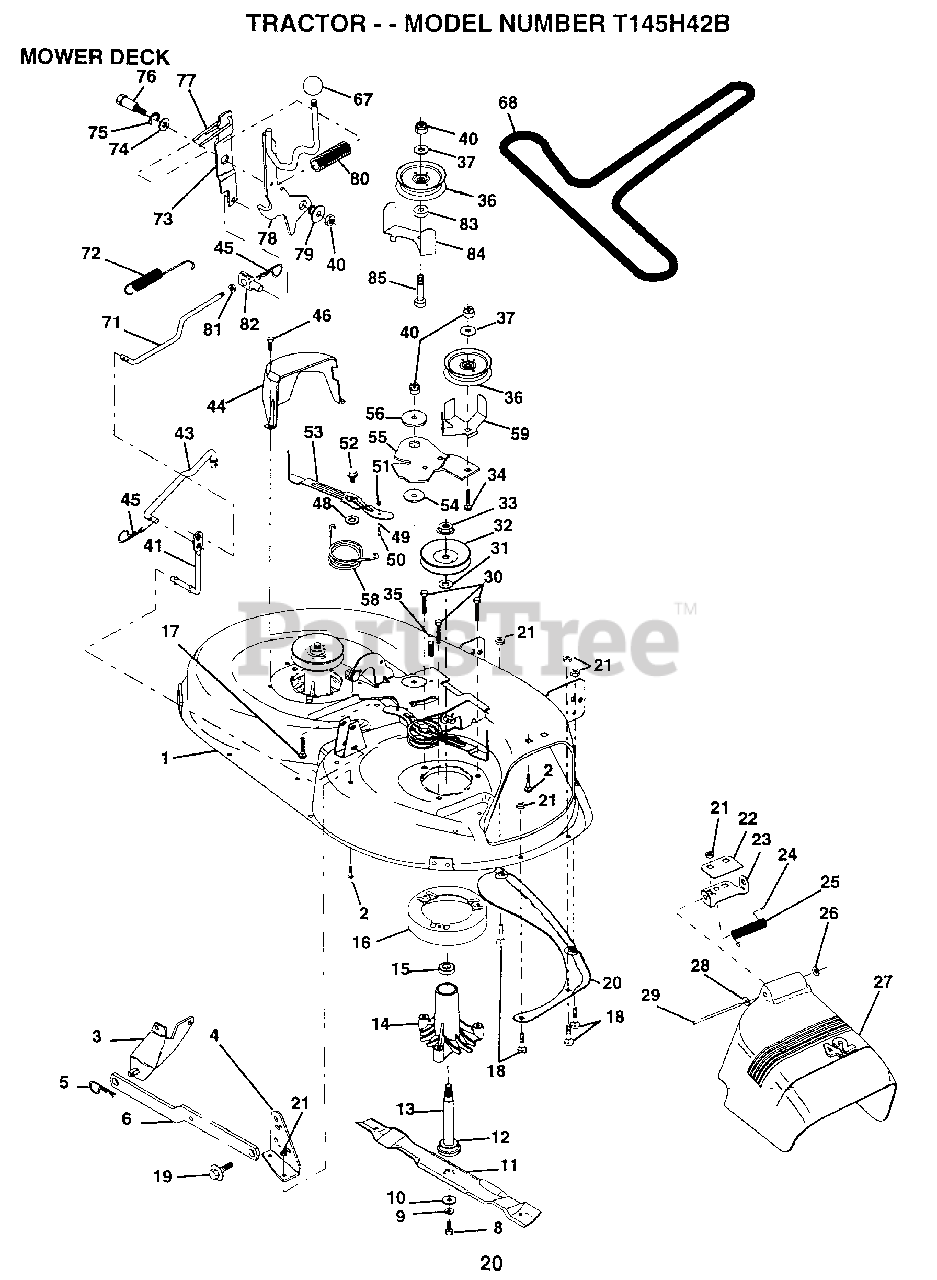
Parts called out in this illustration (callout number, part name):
1	DECK.WELD.42.
2	BOLT
3	BRKT ASM SWAY BAR
4	BRKT DECK SW BAR
8	BLADE BOLT
10	WASHER.HARD.BLADE
11	"BLADE.42"" HIPERF"
12	BEARING.BALL
14	HSG ASM MANDREL
15	BEARING
16	STRIPPER RND MWR
17	BOLT RDHD 3/8-16
18	BOLT
19	BOLT SHD 5/16-18
22	STIFFENER BRKT
23	DEFLECTOR BRKT
24	CAP-SLEEVE LT
25	SPRING TORSION
26	NUT PUSH M
27	DEFLECTOR.SHIELD
28	WASHER
29	HINGE ROD
31	WASHER
32	PULLEY.MANDREL.42
34	BOLT
35	XMAS TREE FASTNER
36	FLAT IDLER PULLEY
37	WASHER
41	PIVOT ROD
43	ROD CLUTCH W/NIBS
44	GUARD MAND LH BLK
45	RETAINER M
46	SCREW.1/4-20X5/8
48	HARD SMALL WASHER
50	SHOULDER BOLT
51	LOCKNUT
52	BOLT.SHLD.5/16-18
53	BRAKE PAD ARM ASM
54	HARDENED WASHER
56	SPACER RETAINER
58	SPRING TORSN BRAK
59	GUARD IDLER TUV
67	CONTROL KNOB LT
68	BELT.V.T-PATH
71	ROD CLUTCH 38/42
72	RETURN SPRING
73	CLUTCH ARM SECOND
74	WASHER
75	RING
76	SHOULDER BOLT
77	SPRING KEEPER
78	LEVER ASM CLT PRM
79	BUSHING
81	NUT
82	TRUNION ADJ
83	WASHER
85	BOLT RDHD 3/8-16
